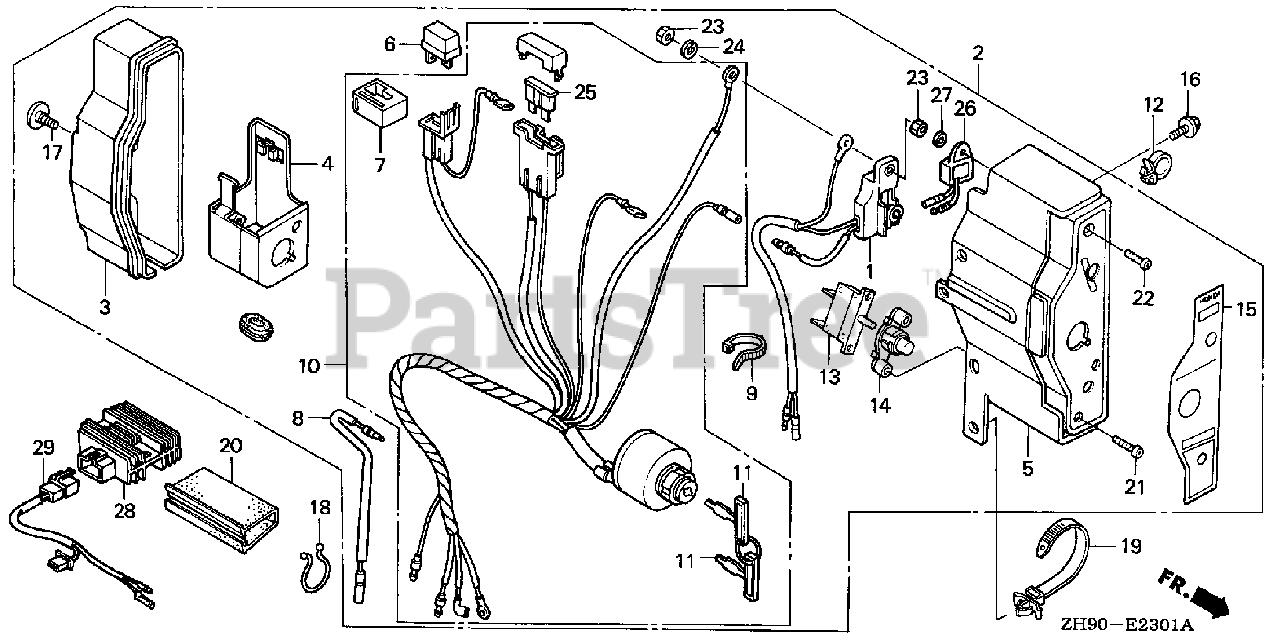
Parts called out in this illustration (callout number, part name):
2	BOX ASSY., CONTROL (EXP-ALERT,3A) *R8* (BRIGHT RED)
3	CASE, CONTROL
4	BRACKET, CASE MOUNTING
5	PANEL, CONTROL *R8**R8* (BRIGHT RED)
6	RECTIFIER ASSY., SILICON (STANLEY)
7	SUSPENSION, CONNECTOR
8	SUB-HARNESS
9	BAND
10	SWITCH ASSY., COMBINATION
11	KEY
12	HOLDER, STOP SWITCH WIRE
13	PROTECTOR, CIRCUIT (3.5A)
14	LENS ASSY., PROTECTOR
15	PANEL, CONTROL BOX (EXTERNAL)
16	BOLT, FLANGE (6X12) (CT200)
17	SCREW, SPECIAL (6X12)
18	CLIP, PURSE LOCK
19	STRAP, CABLE (118MM) *NH1L* (BLACK)
20	TUBE, FASTENER (30)
21	SCREW, PAN (3X12)
22	SCREW, PAN (4X12)
23	NUT, HEX. (4MM)
24	WASHER, SPRING (4MM)
25	FUSE, BLADE (15A)
26	ALERT UNIT, OIL
27	WASHER, PLAIN (4MM)
